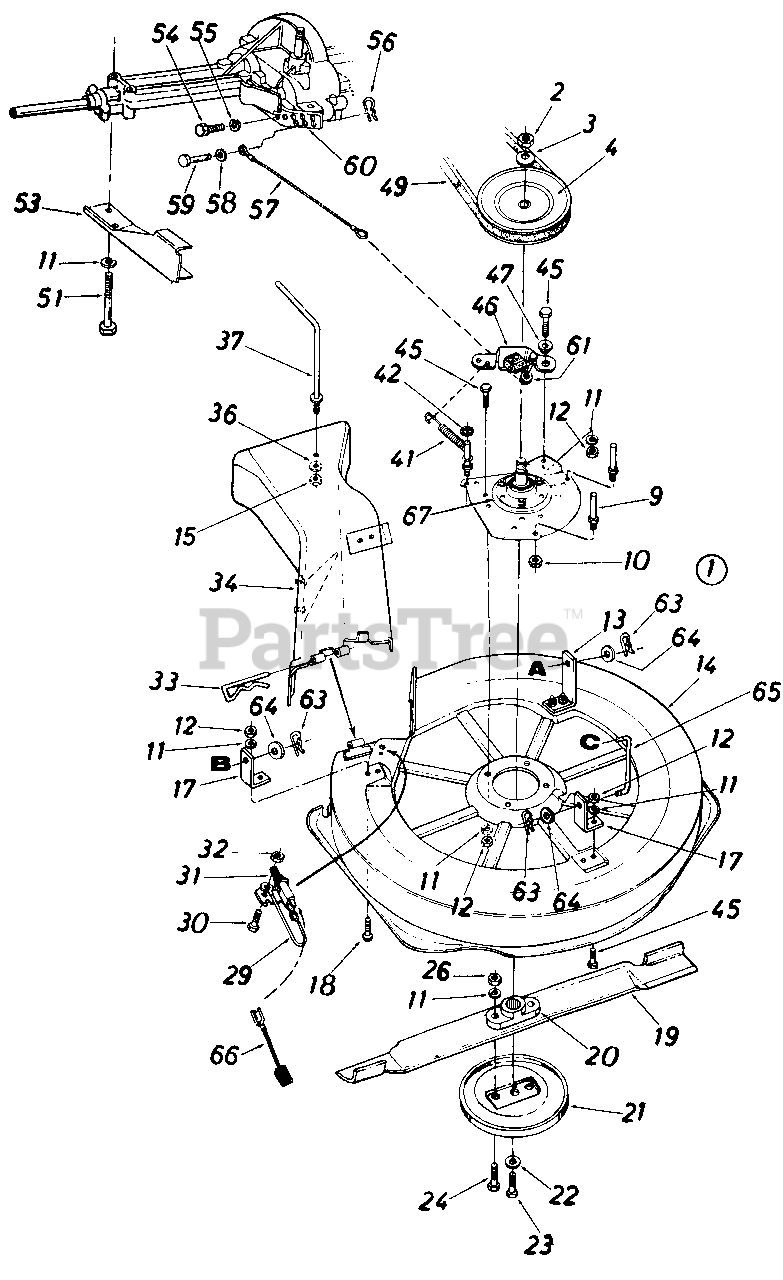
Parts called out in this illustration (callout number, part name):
1	30" R.D. Deck Ass'y. Comp.
2	Hex Jam Nut 5/8-18 Thd.
3	Bell-Wash. .630" l.D. x 1.25"
4	5/8 V-Pulley .75 I.D. x .7"
9	Stud 3/8-16 X 2.75" Lg.
10	Hex Jam Nut 3/8-16 Thd.
11	L-Wash. 5/16 I.D.
12	Hex Nut 5/16-18 Thd.
19	30" High Lift Blade
20	Blade Adapter
21	Scalp Plate
22	L-Wash. 3/8" l.D.
23	Hex Bolt 3/8-24 X 1.0
24	Hex Bolt 5/16-24 X l.On Lg.
26	Hex Nut 5/16-24 Thd.
29	Electrical Wire
30	Hex Bolt 1/4-20 X .50 Lg.
31	Safety Switch
32	Hex Nut 1/4-20 Thd.
33	Internal Cotter Pin
34	R.D. Chute Deflector
36	L-Wash. .32" l.D. x .62 O.D.
37	90ø Rod 5/16-18 Thd.
41	Extension Spring
42	Push Speed Nut
45	Hex Bolt 5/16-18 x .75
46	Blade Brake Brkt. Ass'y.
47	Shoulder Spacer .500" Dia.
49	"V"-Belt 1/2" X 52" Lg.
51	Hex Bolt 5/16-18 x 2.75"
55	L-Wash. 1/4" l.D.
56	Int. Cot. Pin 5/16" Dia.
57	Brake Cable 11.75" Lg.
58	Fl-Wash. .281" l.D. x .50"
59	Clevis Pin 1/4" Dia.
60	Lower Inside Belt Guard
61	Cap Speed Nut 1/4" Rod
63	Int. Cotter Pin 1/2" Dia.
64	Fl-Wash. .531" l.D. x .930n
65	Deck Link 3.9" Lg.
67	Blade Spindle Ass'y. Comp.
